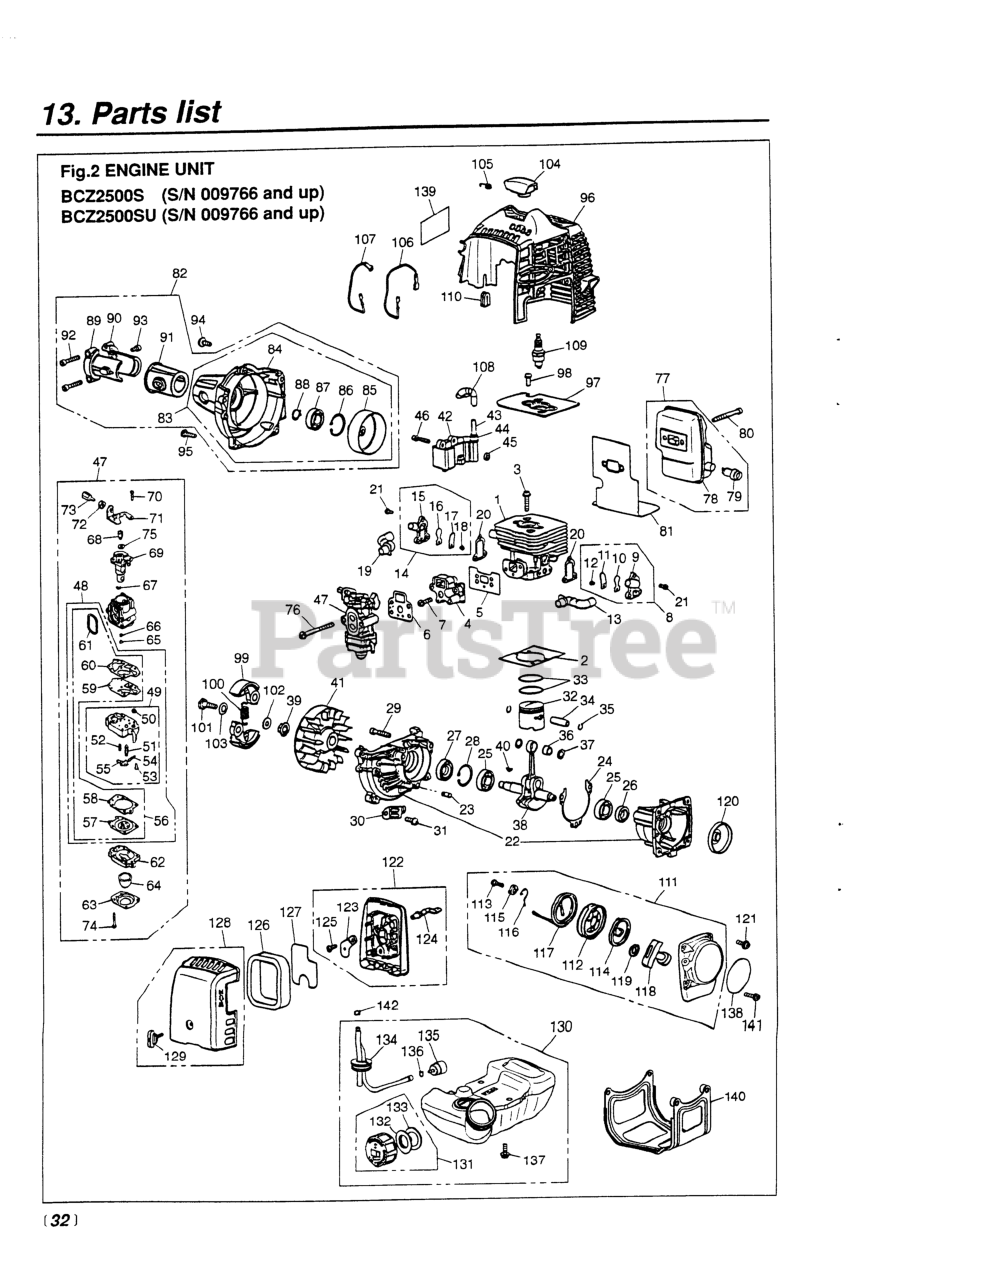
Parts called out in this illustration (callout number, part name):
1	CYLINDER (RPLS -12110)
2	GASKET, BASE
3	BOLT, M5 X 22
4	(REPLACES -13160)(USE -13162)
5	GASKET, INSULATOR
6	GASKET, CARBURETOR
9	CASE VALVE
10	VALVE, REED
11	STOPPER
12	SCREW, M3 x 8
13	PIPE, AIR
16	VALVE, REED
17	STOPPER
18	SCREW, M3 x 8
19	PIPE, AIR (F)
20	GASKET, VALVE
21	SCREW
22	CRANKCASE COMP (USE 4810-21101
23	PIN
24	GASKET
25	BEARING
26	SEAL
27	SEAL, OIL (RPLS 1140-21220)
28	RING, SNAP, M28 x 1.2
29	BOLT, M5 X 30
32	PISTON
33	RING, PISTON
34	PIN, PISTON
35	RING, SNAP (RPLS 1101-41320)
37	WASHER
38	CRANKSHAFT COMPLETE
40	KEY
41	ROTOR
42	COIL-A
43	CORD
44	CAP
45	SPACER (RPLS -71260)
46	BOLT, M4 x 22
49	PUMP BODY ASSEMBLY
50	SCREEN
51	VALVE, INLET
53	SCREW
54	PIN
55	LEVER
57	DIAPHRAGM
58	GASKET, DIAPHRAGM
59	DIAPHRAGM, PUMP
60	GASKET, PUMP
61	RING
62	BODY, PURGE
63	COVER, PUMP
64	PUMP, PRIMING
65	JET (USE -81251)
66	RING, O
67	RING
68	SWIVEL
69	VALVE ASSY
70	SCREW
72	NUT, CABLE ADJUSTER
73	SCREW, CABLE ADJUSTER
74	SCREW
75	WASHER
77	MUFFLER ASSEMBLY
78	MUFFLER (REPLACES -15110)
79	ARRESTER
80	BOLT, M5 x 50
84	COVER, FAN (USE -31111)
86	RING, SNAP, M28 x 1.2
87	BEARING
88	RING, SNAP (RPLS 3130-13270)
89	BRACKET (A) (RPLS -31210)
90	BRACKET (B) (REPLACES -31220)
91	CUSHION
92	BOLT, M5 X 30
93	BOLT (USE 3310-31720)
94	SCREW
96	COVER, ENGINE (RPLS -32110)
97	PLATE
99	SHOE (RPLS 1100-51114)
100	SPRING
101	BOLT
102	WASHER, FLAT (USE 182303)
105	SPRING
106	CORD (BLACK)
107	CORD, EARTH (RED)
110	GROMMET
111	RECOIL ASSEMBLY
112	REEL
113	SCREW
114	SPRING, SPIRAL
115	COLLAR
116	ARM
117	ROPE (REPLACES 4500-75160)
118	KNOB (RPLS -75420)
119	PLATE, STOPPER
120	PULLEY
121	SCREW
122	BODY ASSEMBLY
123	PLATE, CHOKE
124	LEVER, CHOKE
125	SCREW (REPLACES 50030272)
126	ELEMENT
127	SCREEN
128	COVER ASSEMBLY
129	KNOB (RPLS -82220)
130	TANK ASSY (USE -87001)
132	HOLDER (REPLACES -85230)
133	PACKING
134	PIPE COMPLETE
135	FILTER (RPLS 1850-85300)
136	CLIP (REPLACES 2841-31280)
137	SCREW
138	LABEL, RECOIL
139	LABEL, COVER (RPLS -31130)
142	CLIP
